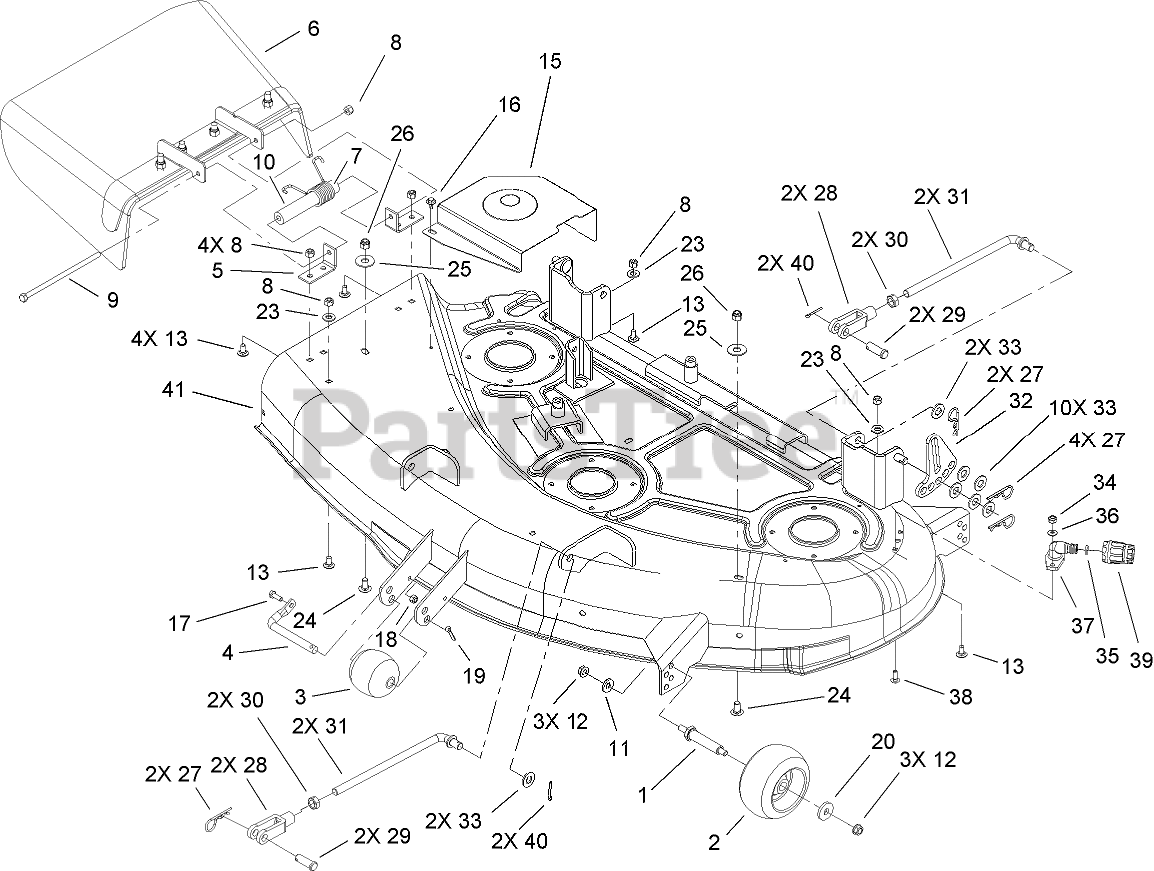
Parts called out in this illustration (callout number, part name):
1	SPACER
2	ROLLER-SCALP, ANTI
3	ROLLER
4	Shaft-Roller
5	BRACKET-PIVOT, DEFLECTOR
6	DEFLECTOR ASM
7	SPRING-TORSION
8	NUT-LOCK, NI
9	BOLT-HH
10	SPACER-DEFLECTOR
11	WASHER-BELLEVILLE
12	NUT-HHF, WHIZ
13	SCREW-CARR
15	COVER-BELT, RH
16	SCREW-HHFTF
17	SCREW-HH
18	NUT-LOCK, NI
19	PIN-COTTER
20	WASHER
23	WASHER-FLAT
24	SCREW-CARR
25	WASHER-FLAT
26	NUT-LOCK, NI
27	PIN-COTTER
28	CLEVIS
29	PIN-CLEVIS
30	NUT-JAM
31	ROD-TRUNION
32	LINK-HOC, ADJUSTING
33	WASHER-FLAT
34	NUT-LOCK, NI
35	O-RING
36	WASHER-FLAT
37	FITTING-WASHOUT
38	BOLT-CARR
39	CONNECTOR-HOSE
40	PIN-COTTER
41	44 INCH DECK ASM
